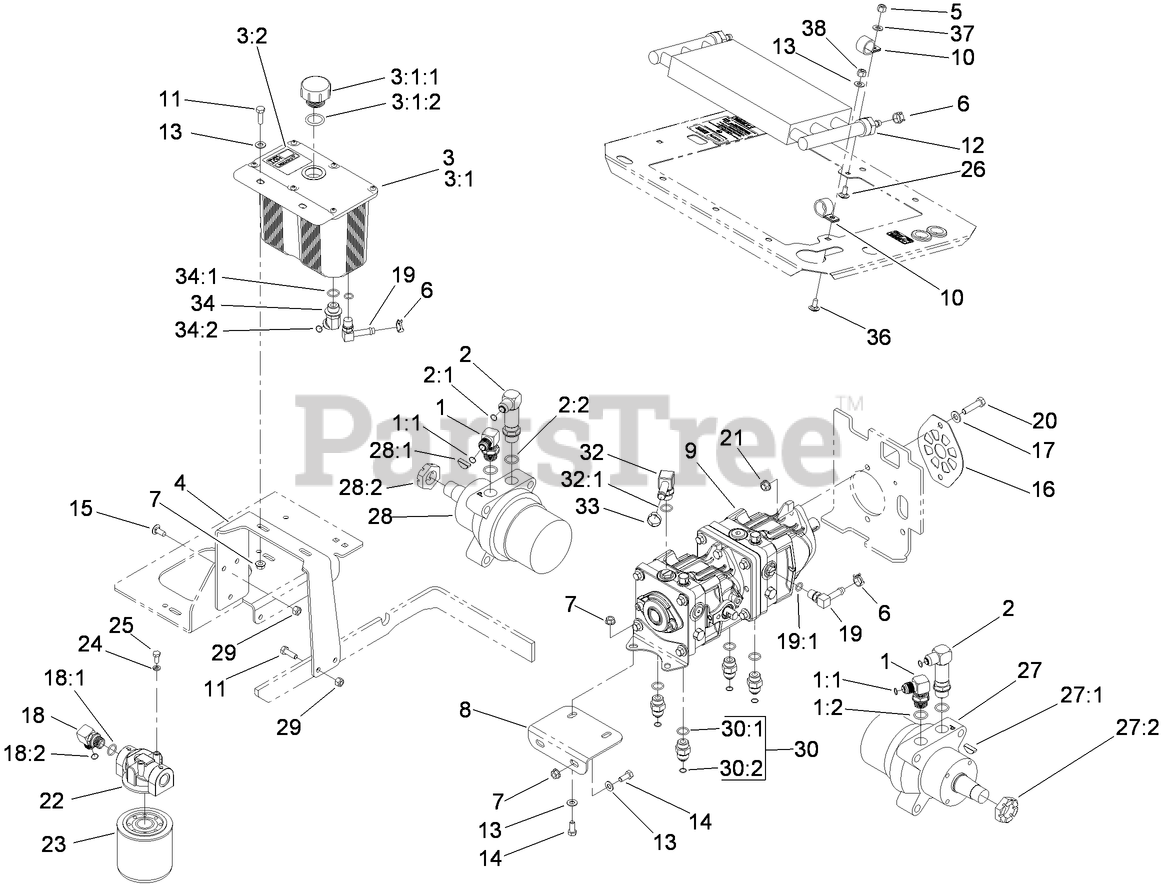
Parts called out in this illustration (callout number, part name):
1	FITTING-HYD, 90 DEG
1:1	O-Ring
1:2	O-RING
2	FITTING-ELBOW-90
2:1	O-Ring
2:2	O-RING
3	HYDRAULIC TANK ASM
3:1	TANK-HYDRAULIC
3:1:1	CAP-RESERVOIR, HYD
3:1:2	GASKET-CAP
3:2	DECAL-TANK, HYD
4	BRACKET-TANK, HYDRAULIC
5	NUT-LOCK, NI
6	CLAMP-HOSE
7	NUT-HF
8	BRACKET-PUMP, FRONT
9	TANDEM PUMP ASM
10	R-CLAMP
11	SCREW-HH
12	COOLER-OIL, HYDRO
13	WASHER-PLAIN
14	SCREW-HH
15	SCREW-CARR
16	PLATE-SHIELD, PUMP
17	WASHER-FLAT
18	FITTING-90 DEG
18:1	O-RING
18:2	O-Ring
19	FITTING-ELBOW, 90
19:1	O-RING
20	SCREW-HH
21	NUT-HHF, WHIZ
22	HEAD-FILTER
23	CARTRIDGE-FILTER, OIL
24	WASHER-LOCK
25	SCREW-HH
26	SCREW-CARR
27	HYD MOTOR ASM (CCW)
27:1	KEY-WOODRUFF
27:2	NUT-HH
28	HYD MOTOR ASM (CW)
28:1	KEY-WOODRUFF
28:2	NUT-HH
29	NUT-LOCK, NI
30	FITTING-STRAIGHT
30:1	O-RING
30:2	O-Ring
32	FITTING-ELBOW, 90 DEG
32:1	O-RING
33	CLAMP-HOSE
34	FITTING-HYD, 45 DEG
34:1	O-RING
34:2	O-Ring
36	SCREW-CARR
37	WASHER-FLAT
38	NUT-LOCK, NI
